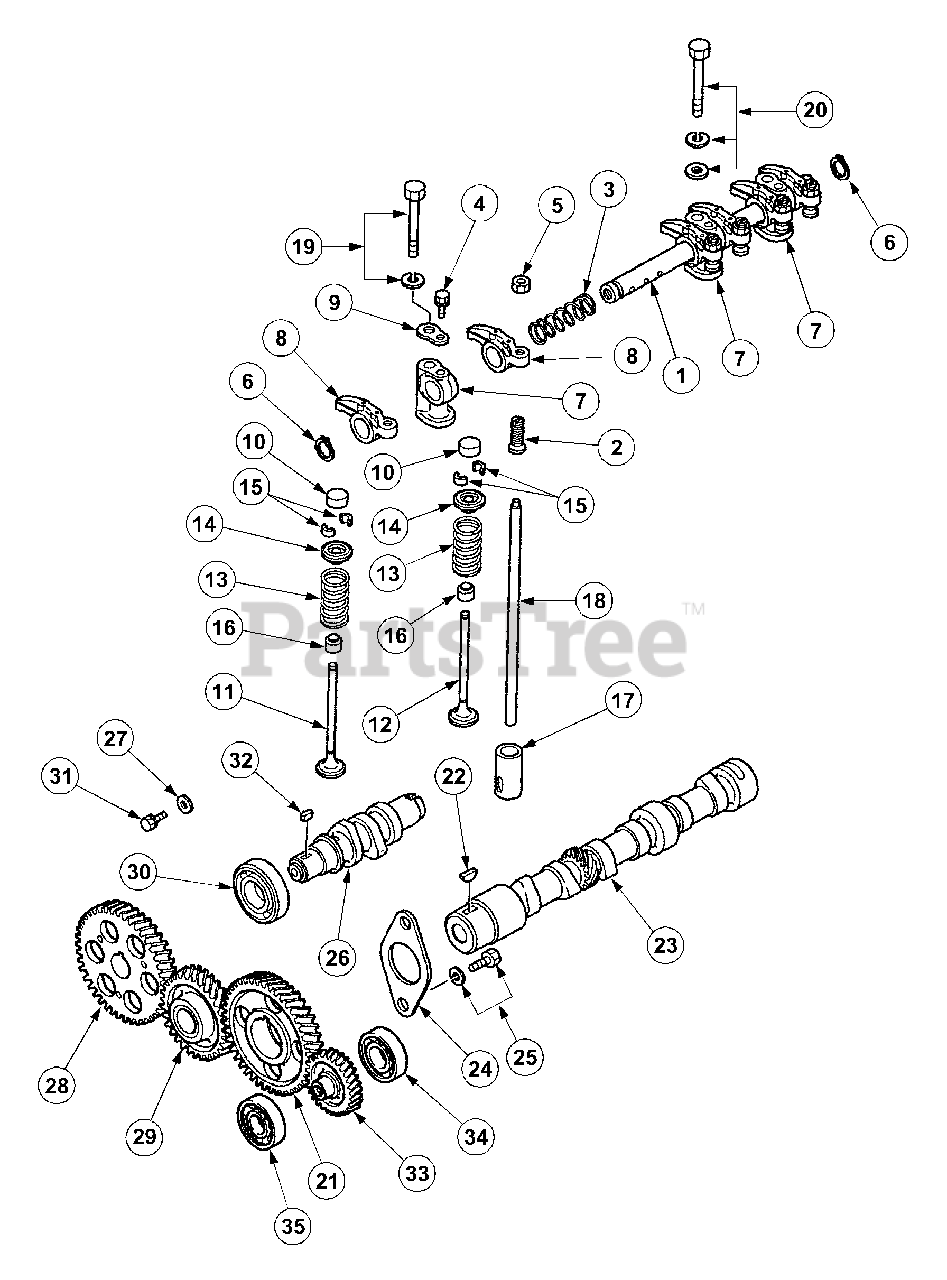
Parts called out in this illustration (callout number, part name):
1	Shaft Assy,Rocker
2	Screw,Adjusting
3	Spring,Rocker
4	Bolt,w/Washer
5	Nut,Jam
6	Ring,Snap
7	Stay,Rocker
12	Valve,Exhaust
13	Spring,Valve
14	Retainer,Valve
16	Seal,Valve
17	Tappet
19	Bolt,w/Washer
20	Bolt,w/Washer
21	Gear,Camshaft
25	Bolt,w/Washer
28	Gear,Injection
29	Gear Assy,Idler
31	Bolt,w/Washer
33	Gear,Pressure Oil Pump
